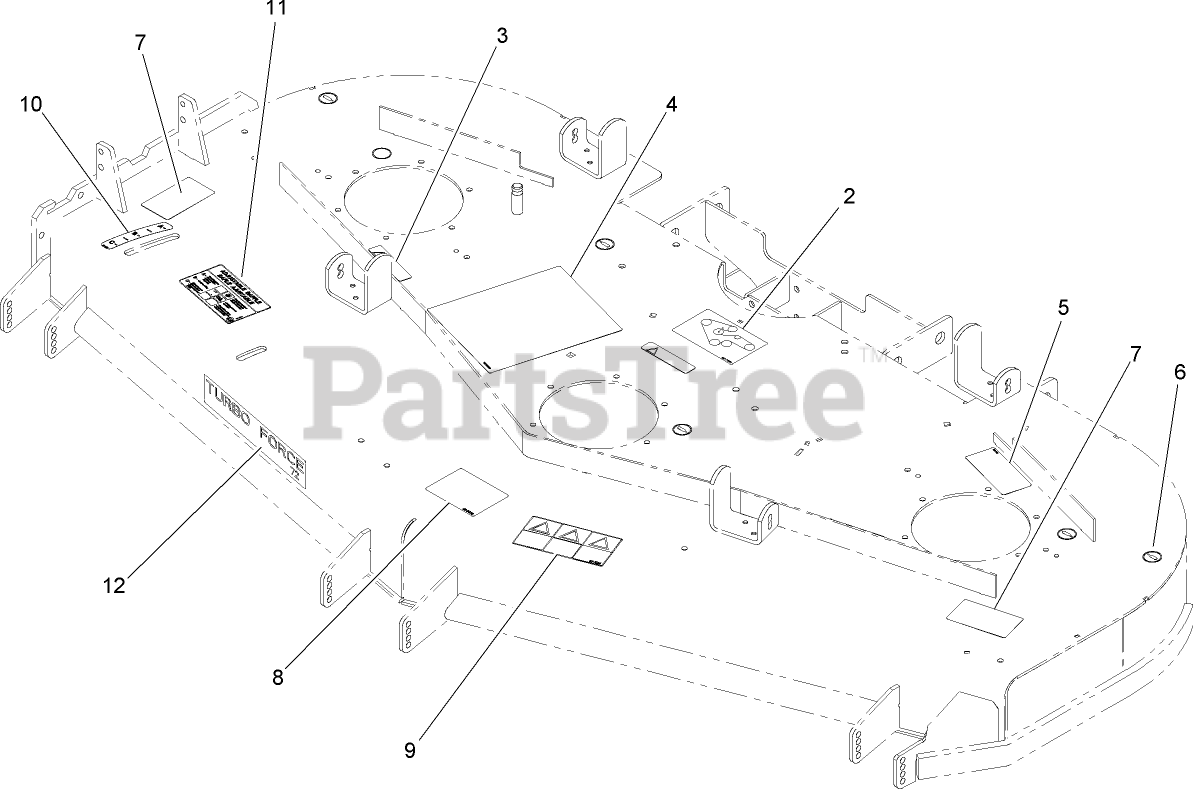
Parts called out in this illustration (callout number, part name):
2	DECAL-ROUTING, BELT
3	DECAL-WARNING
4	DECAL-CHECK, SERVICE
5	DECAL-TORQUE, BLADE BOLT
6	DECAL-GREASE
7	DECAL-DANGER
8	DECAL-ANTI SCALP
9	DECAL-DANGER
10	DECAL-SETTING, BAFFLE
11	DECAL-ADJUSTMENT, BAFFLE
